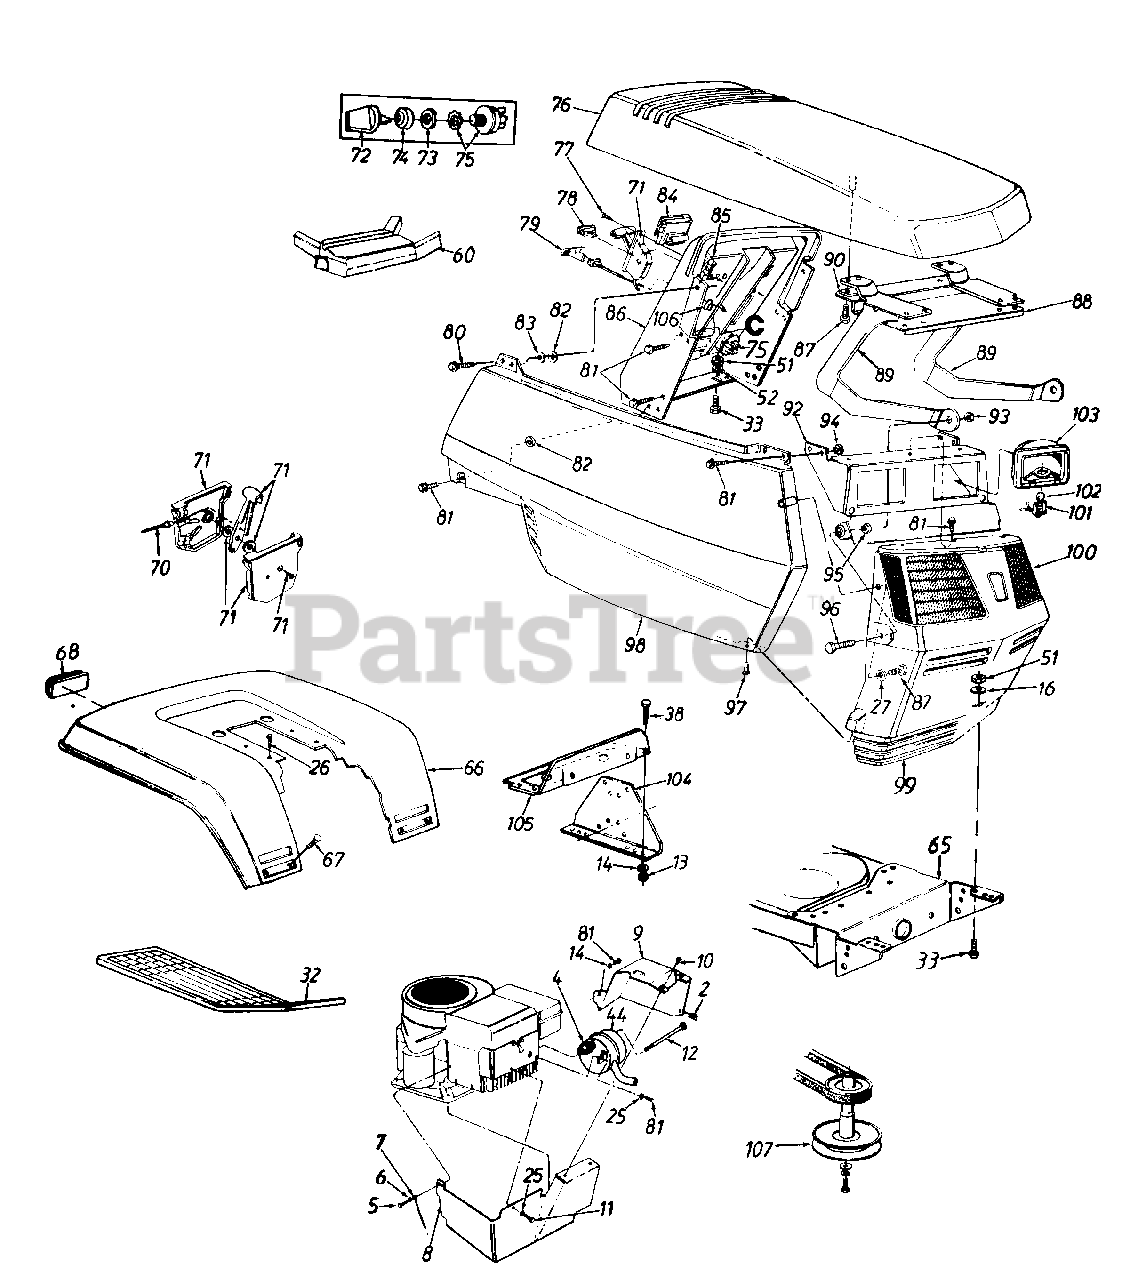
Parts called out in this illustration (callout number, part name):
2	Speed Nut #10-24 Thd.
4	Gasket
5	Truss Mach. Scr. 5/16-18 x .75"
6	External L-Wash. 5/16" I.D.
7	Ground Wire
8	Muffler Heat Shield - Front
9	Muffler Heat Shield - L.H.
10	Hex Wash. Tap Scr. #10 x .5" Lg
11	Hex Bolt 1/4-20 x 3/8" Lg.
12	Shld. Bolt 7/16" Dia. x 3-5/8" Lg
13	Hex Nut 1/4-20 Thd.
14	L-Wash. 1/4" I.D.
16	Fl-Wash. .344" I.D. x 1" O.D.
25	Spr. Wash. .265" I.D.
26	Hex Wash. Hd. AB-Tap Scr. 5/16 x .75" Lg.
27	Fl-Wash. .218" I.D. x .5" O.D.
32	Rubber Foot Pad - L.H.
33	Hex Bolt 5/16-18 x .75" Lg.
38	Hex Bolt 1/4-20 x .62" Lg.
44	Muffler
51	Hex Nut 5/16-18 Thd.
52	Fl-Wash. .343" I.D. x .687"
60	Steering Wheel Insert
68	Reflector
70	Throttle Wire 18.5" Lg.
71	Throttle Control Box Ass'y.
72	Ignition Key
73	Ignition Switch Nut
74	Ignition Switch Cap
75	Ignition Switch
76	Hood
77	Truss Mach. AB-Tap Scr. #10 x .5" Lg.
78	Light Switch
79	Choke Control
80	Hex Wash. Hd. Tap Scr. 1/4 x .75" Lg.
81	Hex Tap Scr. 1/4-20 x .5" Lg.
82	Push Nut Fastener
83	Fl-Wash. .27" I.D. x .948"
84	Ammeter
85	Speed Nut 1/4-20 Thd.
86	Dash Panel
87	Hex Wash. Hd B-Tap Scr. 1/4 x .62" Lg.
94	Hex L-Nut 1/4-20 Thd.
95	Hex Jam Nut 5/16-18 Thd.
96	Hex Bolt 5/16-18 x 7/8" Lg.
97	Truss Mach. B-Tap Scr. #10 x .5" Lg.
98	Side Cover - R.H.
99	Grille
100	Lens - L.H.
101	Twist Lock - Lamp Socket
102	Lamp
103	Headlight Housing
107	Engine Pulley (30" Deck Only)
